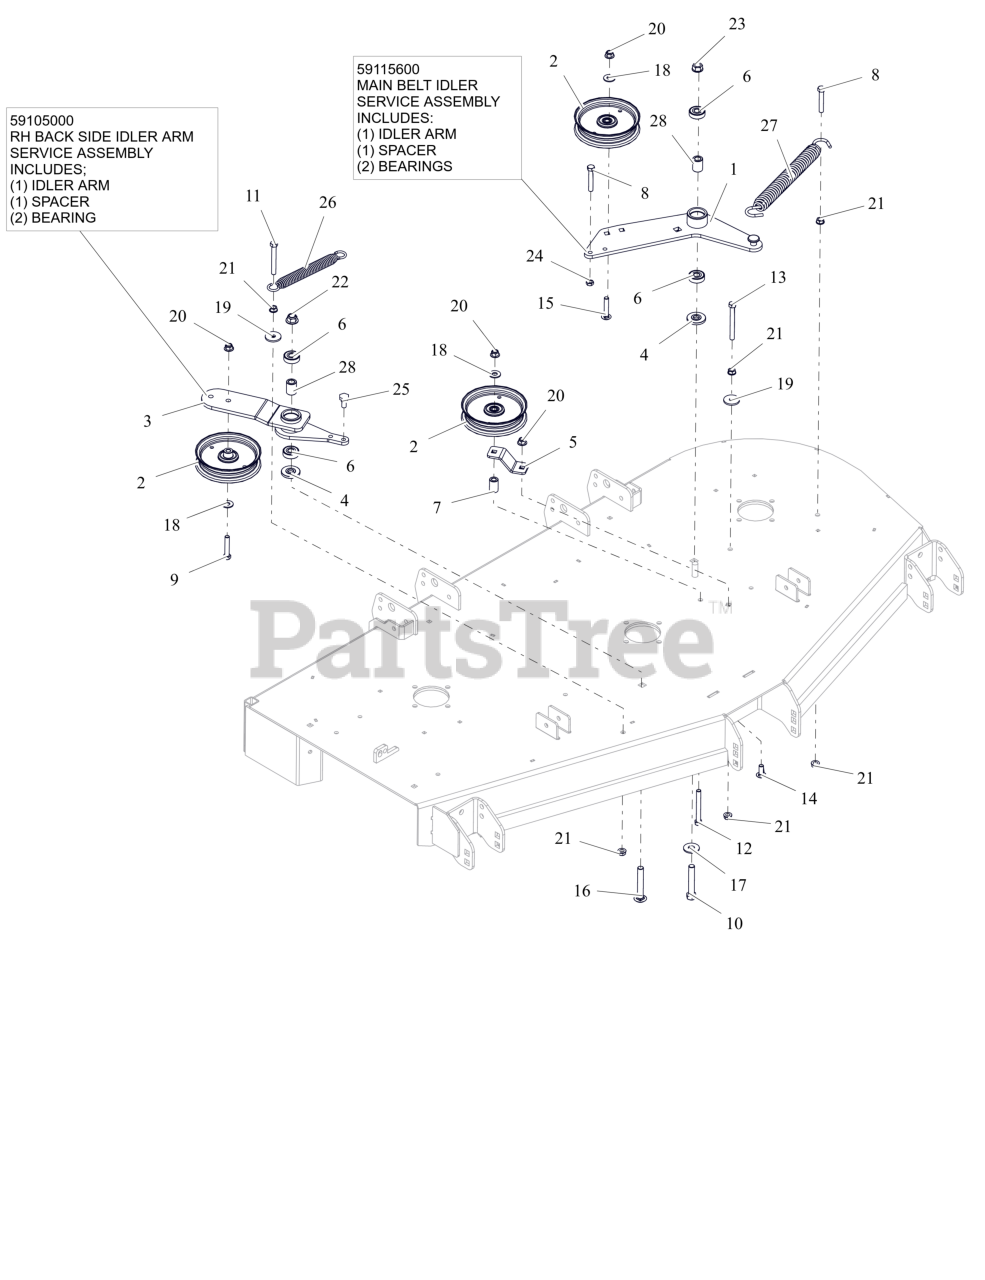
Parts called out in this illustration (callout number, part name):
1	WLDMT, DECK PTO IDLR ARM
1	ASSEMBLY, MAIN BELT IDLER
1	SPACER .510 X .867 X 1.1485
1	BRG-BALL .500X1.38X.437
2	IDLER- FLAT - 5.00" X .75"
3	WLDMT, DECK RH IDLER ARM
3	RH BACKSIDE IDLER ARM ASSEMBLY
3	SPACER .510 X .867 X 1.1485
3	BRG-BALL .500X1.38X.437
4	SPACER, IDLER ARM
5	PTO FIXED IDLER MTG BRKT -RED
6	BRG-BALL .500X1.38X.437
7	BUSHING, SLV .380X.750X1.190
8	BLT,HEX .38-16X2.25 G5 ZCC
9	BLT,HEX .38-16X2.00 G5 ZCC
10	BLT, HEX .50-13X3.00 G5 ZCC
11	BLT, HEX .38-16X3.00 G5 ZCC
12	BLT, HEX .38-16X3.25 G5 ZCC
13	BLT, HEX .38-16X3.50 G5 ZCC
14	BLT,RHSSN .38-16X1.00 G5 ZCC
15	BLT,RHSSN.375-16X2.00 G5 ZCC
16	BTL,RHSSN .500-13 X 3.25 G5 ZCC
17	WSHR,FLT .563X1.375X.109 ZCC
18	WSHR,FLT .438X1.00X.083 ZCC
19	WSHR,FLT .406X1.375X.135 ZCC
20	NUT,NYL-FLG .38-16 GF ZCC
21	NUT, SPNLK-FLG .38-16 G5 ZCC
22	NUT,NYL-FLG .50-13 GF ZCC
23	NUT-LK-CTR-FLG .500-13 GG ZCC
24	NUT-JAM .375-16 G2 ZCC
25	BLT,SHLDR EP .38-16X.30 HEX YZ
26	SPRING- EXTENSION
27	SPRING, EXTENSION
28	SPACER .510 X .867 X 1.1485
